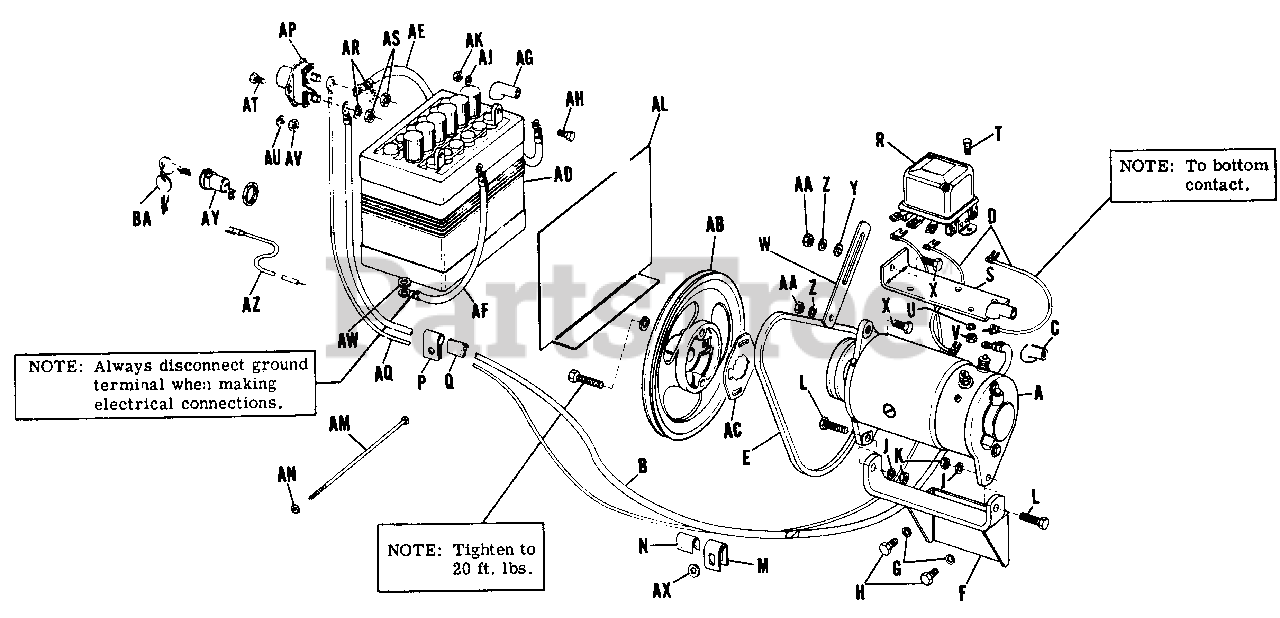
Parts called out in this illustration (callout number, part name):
A	Motor-Generator
B	Cable, Switch to Generator
C	Cover, Terminal
E	Belt, "V"
F	Support Assembly
G	Washer, Lock, 5/16"
H	Screw, Cap, Hex., 5/16"-18 N.C. x 3/4" lg.
J	Washer, Lock, 5/16"
K	Nut, Full, Hex., 5/16"-18 N.C.
L	Screw, Cap, Hex., 5/16"-18 N.C. x 1-1/4" lg.
M	Clamp, Cable
N	Lining, Clamp
P	Clip, Cable
Q	Lining, Clip
R	Regulator, Voltage
S	Bracket, Voltage Regulator
T	Screw, Cap, Hex., 1/4"-20 N.C. x 1/2" lg.
U	Washer, Lock, 1/4"
V	Nut, Hex., Full, 1/4"-20 N.C.
W	Tightener, Belt
X	Screw, Cap, Hex., 5/16"-18 N.C. x 3/4" lg.
Y	Washer, Plain, 5/16"
Z	Washer, Lock, 5/16"
AA	Nut, Hex., Full, 5/16"-18 N.C.
AB	Pulley, Engine
AC	Nut, Lock
AE	Cable, w/cover
AG	Cover, Terminal
AH	Screw, Cap, Hex., 1/4"-20 N.C. x 5/8" lg.
AJ	Washer, Lock, 1/4"
AK	Nut, Hex, Full, 1/4"-20 N.C.
AL	Gasket, Tank
AM	Bolt, Mach., 1/4"-20 N.C. x 7-3/4" lg.
AN	Nut, Lock, Full, Hex., 1/4"-20 N.C.
AP	Switch, Starting
AQ	Wire, Starting Switch to Regulator
AR	Washer, Lock, 3/8"
AS	Nut, Hex., Full, 3/8"-16 N.C.
AT	Screw, Cap, Hex., 1/4"-20 N.C. x 1/2" lg.
AU	Washer, Lock, 1/4"
AV	Nut, Hex., Full, 1/4"-20 N.C.
AW	Washer, Plain, 1/4"
AX	Washer, Plain, 5/16"
AY	Switch, Ignition, w/keys
AZ	Wire Switch
BA	Set, Ignition Keys
